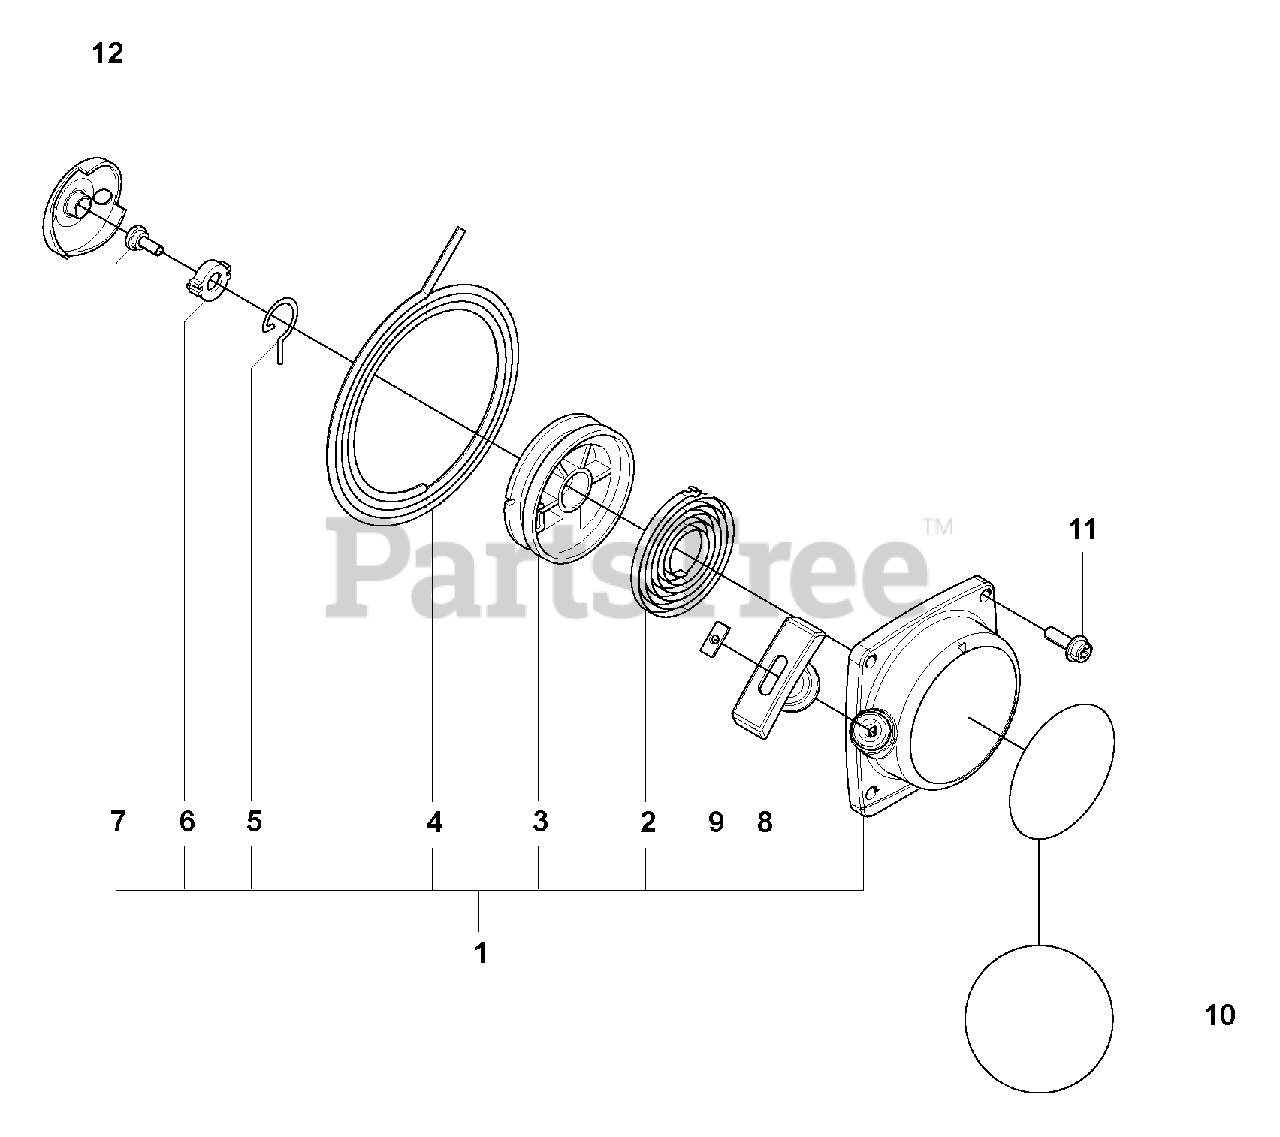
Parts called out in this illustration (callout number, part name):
1	RECOIL A
6	COLLAR
7	SCREW
9	SPRING, SPIRAL
10	LABEL RECOIL
11	BOLT
